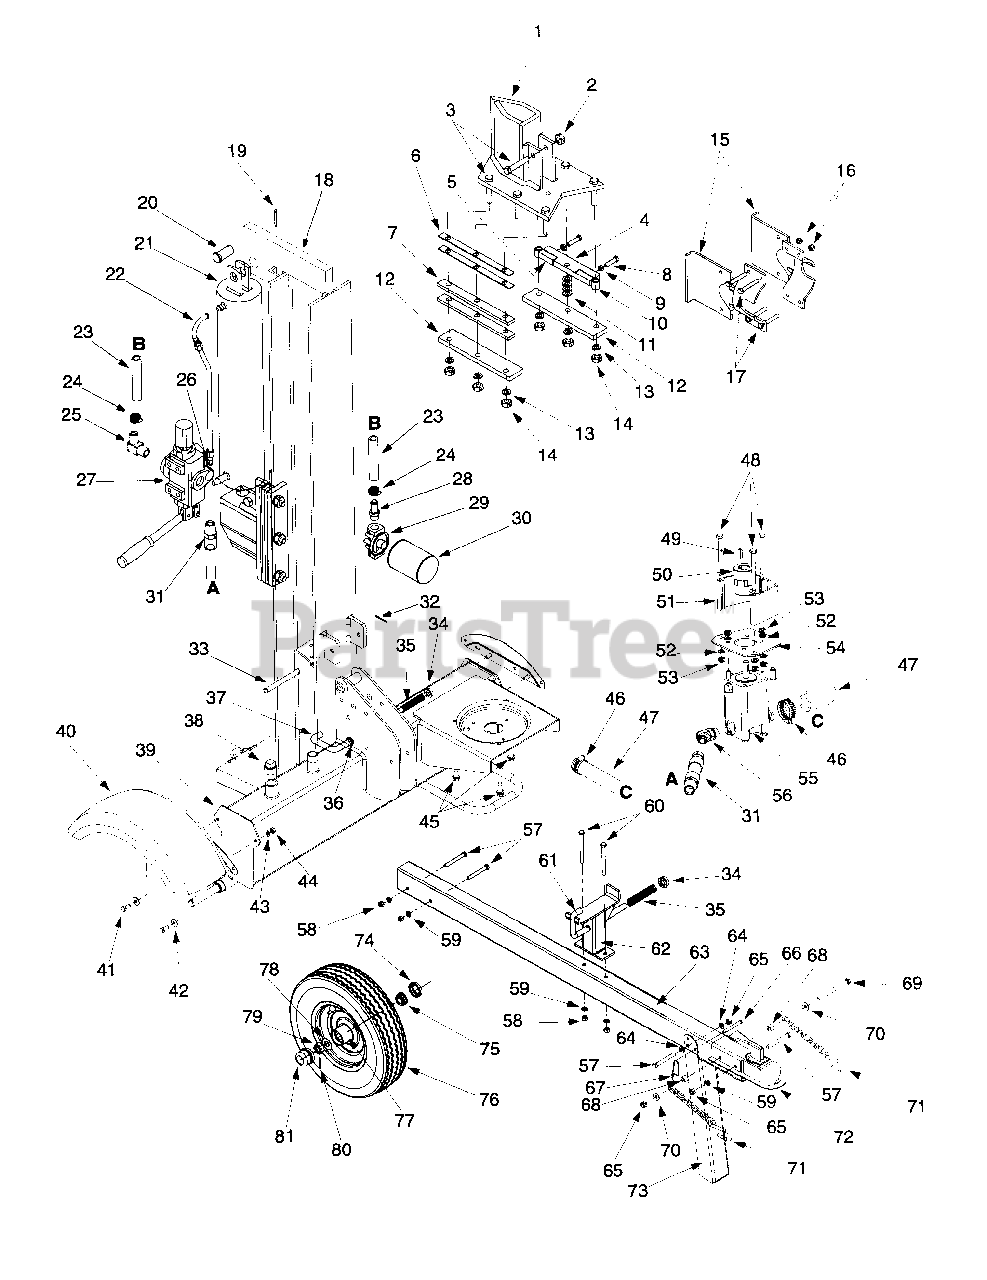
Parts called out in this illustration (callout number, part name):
2	Lock Nut 1/2-20
3	Hex Cap Screw 1/2-20 x 2.75
8	Hex Cap Screw 3/8-24 x 1.5
9	Hex Jam Nut 3/8-24
10	Spacer
11	Flat Washer .531 x .93 x .090
13	Lock Washer 1/2
14	Lock Nut 1/2-20
17	Hex Cap Screw 3/8-16 x 2.5
20	Clevis Pin
23	Return Hose 3/4" ID x 44" Lg
24	Hose Clamp 5/8"
25	Return Elbow
26	90 Degree Solid Male Adapter
28	3/4" Hose Adapter
29	Filter Housing
30	Oil Filter
31	High Pressure Hydraulic Hose
32	Cotter Pin 1/8" Dia
33	Hinge Pin 1/2 x 4.8" Lg.
34	Push Cap
35	Comp. Spring 4" Lg.
36	Flat Washer .635 ID X .93 OD
37	Locking Rod
38	Pipe Plug
42	5/16 Washer
43	Lock Washer 5/16
44	Hex Nut 5/16-24
45	Hex Washer Screw 3/8-16 x 1.0
46	Hose Clamp
47	Suction Hose
48	Hex Screw 5/16-24 x 3.25
49	Sq. Key 3/16" x .75
50	Flexible Coupling
51	Coupling Shield
52	L-Washer 5/16" ID
53	Hex Nut 5/16-24
55	Gear Pump (11 gpm)
56	45 Degree Elbow
57	Hex Bolt 3/8-16 x 3" Lg.
58	Hex Nut 3/8-16
59	L-Washer 3/8" 10
60	Hex Bolt 3/8-16 x 4" Lg.
61	Locking Rod
64	Flat Washer 3/8
65	Hex Lock Nut 3/8-16
66	Clevis Pin 5/16 x 2.5"
67	Spring Pin
68	Spacer 3/8" ID x .625' OD
69	Hex Bolt 3/8-16 x 4" Lg.
70	Flat Washer 3/8" ID x .87" OD
71	Chain - Tow Hitch
72	Hitch Coupler
75	Bearing Cone
76	Wheel Asm Comp - Gray
77	Bearing Cup
78	Flat Washer .76" ID x 1.5" OD
79	Slotted Nut 3/4-16
80	Cotter Pin 5/32" x 1-1/4" Lg.
81	Hub Cap
